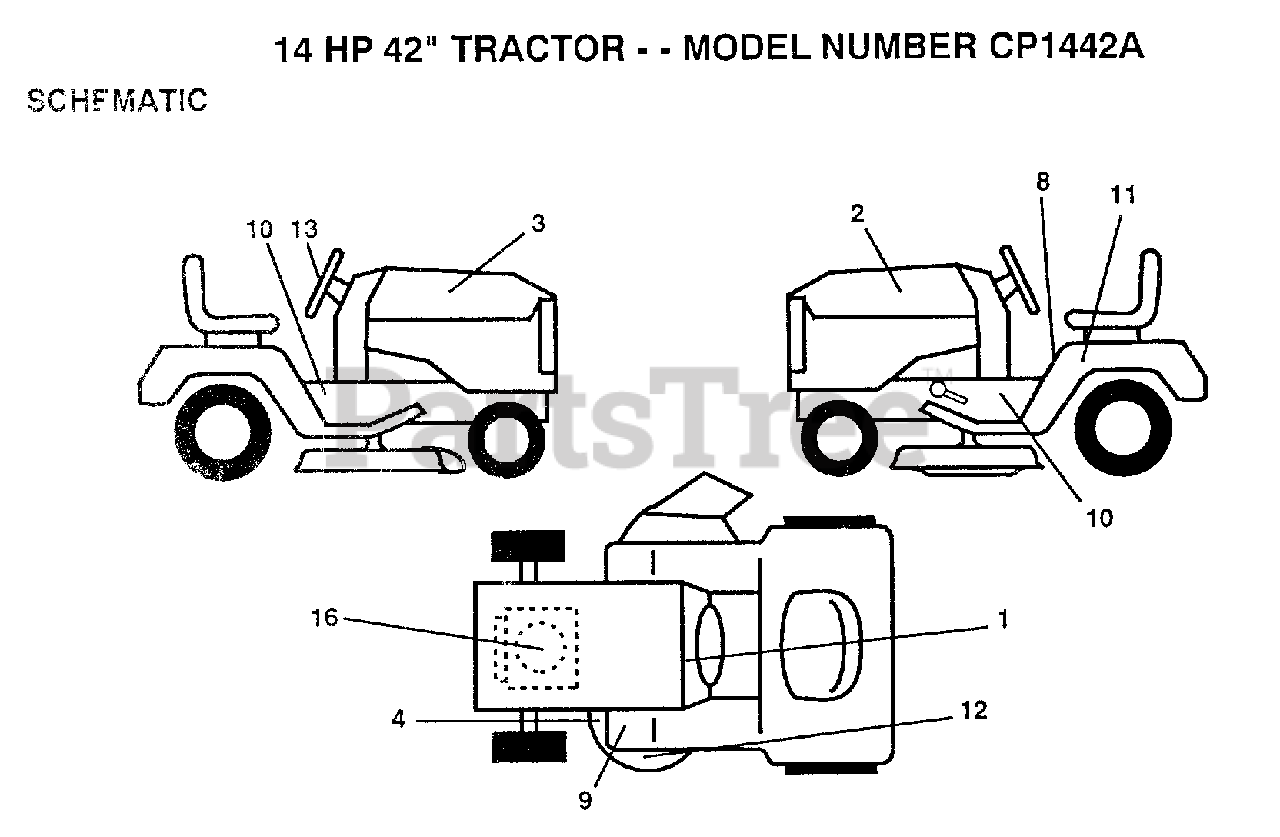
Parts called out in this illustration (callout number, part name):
1	DECAL.DASH.INST.
2	DECAL, HOOD LH
3	DECAL, HOOD RH
4	DECAL
8	DECAL
10	CHASSIS DECAL
11	DECAL.FEND.QUICK.
16	DECAL.ENG.272613
